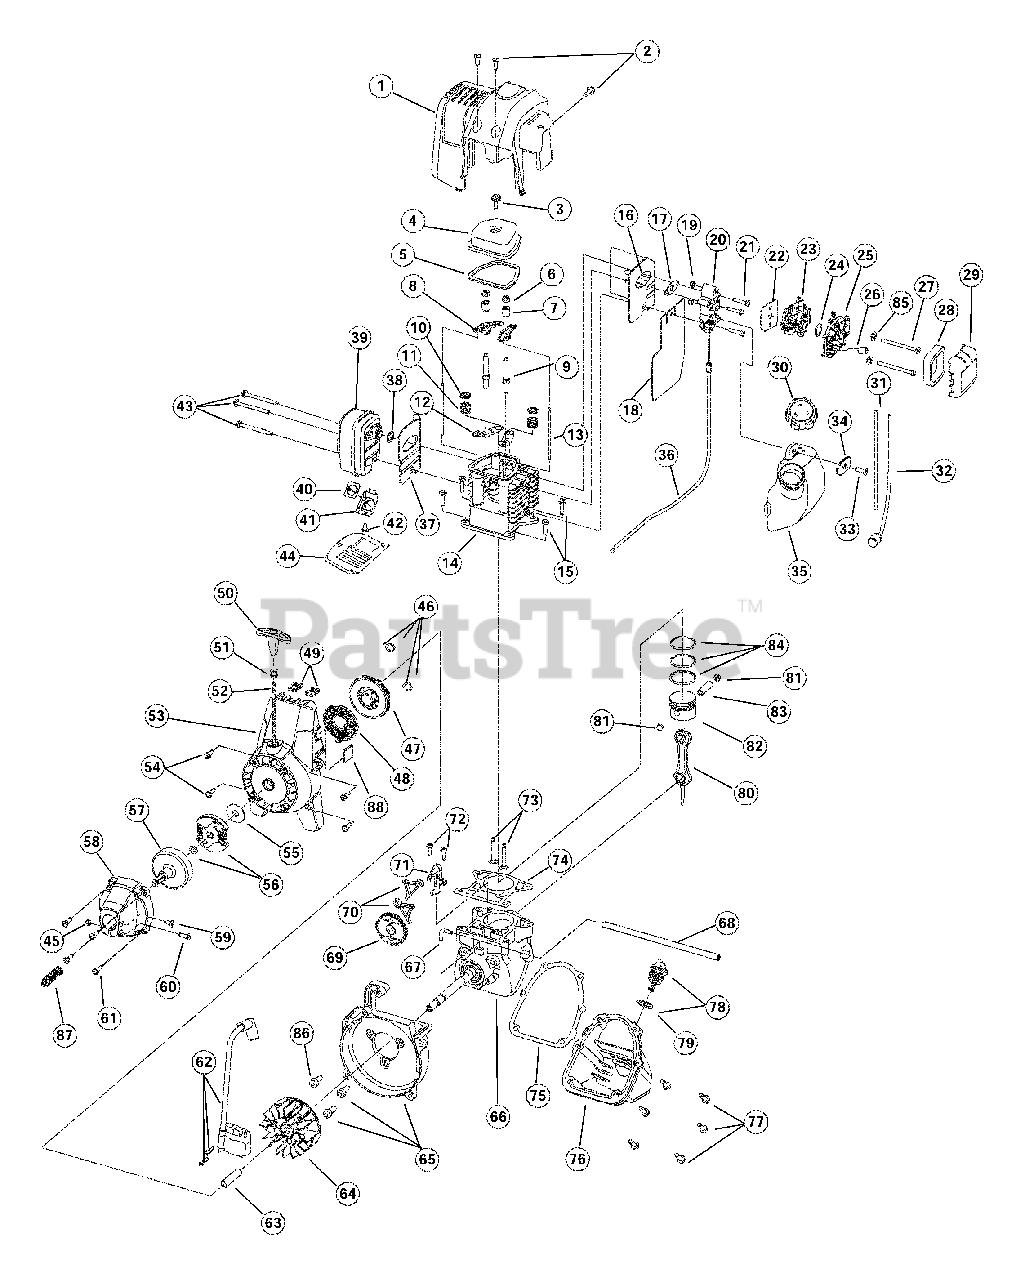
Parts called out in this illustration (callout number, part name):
1	Engine Cover
2	Engine Cover Screws
3	Valve Cover Screw
4	Valve Cover
5	Valve Cover Gasket
6	Rocker Adjustment Nut
7	Rocker Arm Pivot
8	Rocker Arm
9	Rocker Arm Stud
10	Valve Spring Retainer
11	Valve Spring
12	Push Rod Guide
13	Push Rod
14	Cylinder Assembly
15	Cylinder Screw
16	Intake Baffle
17	Carburetor Mount Gasket
18	Muffler Baffle
19	Nut
20	Carburetor Mount
21	Carburetor Mount Screw
22	Carburetor Gasket
23	Carburetor with Primer
24	O-Ring, Carburetor
25	Air Filter/Choke Cover Assembly
26	Breather Tube
27	Air Filter Mounting Screw
28	Air Filter
29	Air Filter Cover
30	Fuel Cap
31	Fuel Return Line
32	Fuel Pick-Up Line with Filter
35	Fuel Tank Assembly
36	Fuel Tank Shield
37	Throttle Cable
38	Muffler Gasket
39	Muffler
40	Spark Arrestor Screen
41	Screen Cover
43	Muffler Mounting Screw
44	Muffler Cover
46	Pal Nut Retaining Ring
47	Recoil Pulley
49	Recoil Spring
49	Nut Clip
50	Pull Handle
51	Rope Guide
52	Starter Housing Screw
54	Starter Housing Assembly
55	Clutch Washer
56	Clutch with Spacer
57	Clutch Drum
58	Clutch Cover
59	Anti-Rotation Screw
60	Screw
61	Clutch Cover Screw
62	Ignition Module with Screws
64	Flywheel
65	Shroud Assembly with Screws
66	Crankcase Assembly
67	Oil Seal
68	Bearing
69	Crankshaft Assembly
70	Cam Follower
71	Cam Bracket
72	Cam Bracket Screw
73	Valves, Intake and Exhaust
74	Cylinder Gasket
75	Oil Pan Gasket
76	Oil Pan
77	Oil Pan Screw
78	Dipstick Assembly
80	Connecting Rod
81	Wrist Pin Button
82	Piston
83	Wrist Pin
84	Piston Ring Set
87	Compression Spring
88	Grommet
